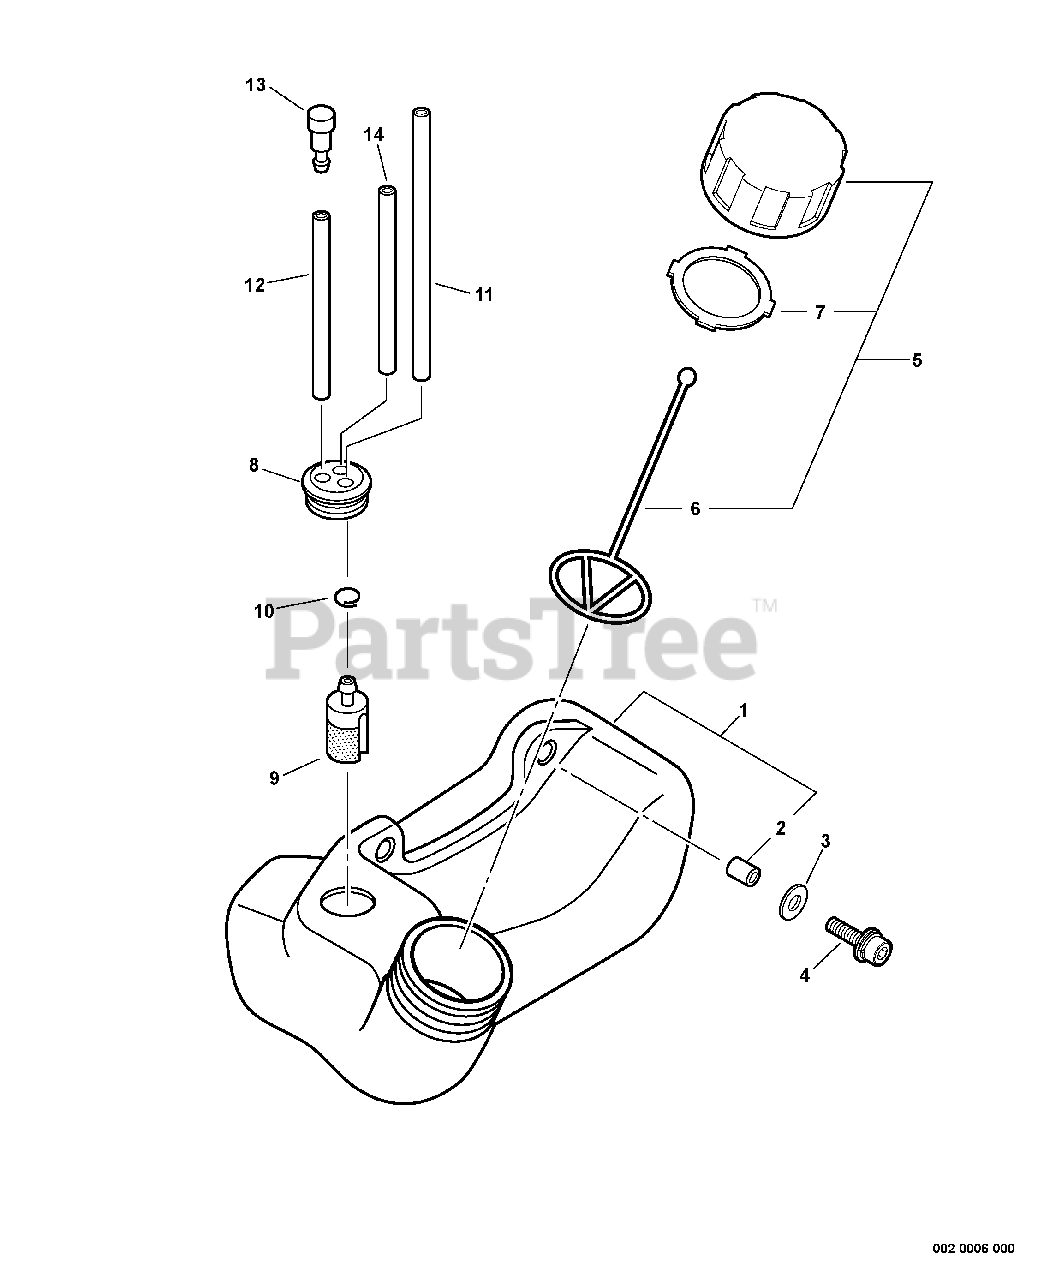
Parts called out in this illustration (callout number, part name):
1	FUEL TANK ASSY
3	WASHER - 5
4	SCREW - 5X16
5	CAP ASSY - ORANGE
6	CONNECTOR, CAP
7	GASKET, CAP
8	GROMMET
9	FILTER, FUEL
10	CLIP - 6
11	PIPE - 3X5X180 -- BLACK
12	PIPE - 3X5X70 -- BLACK
13	VENT, FUEL TANK
14	PIPE - 3X6X80 -- CLEAR
